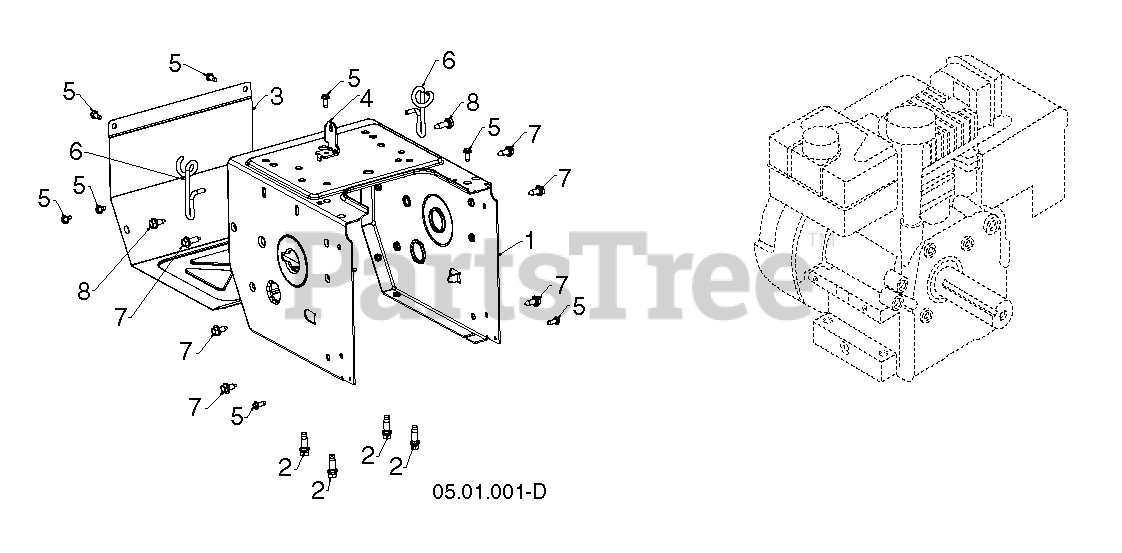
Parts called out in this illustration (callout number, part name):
1	FRAME.GEAR.CASE.ORANGE
2	BOLT 3/8-16X1-1/8
3	COVER COVER.FRAME MS668 ORANGE
4	BRACKET.SHIFTER.SNOW.BLACK
5	SCREW 14-20 X 5/8
6	RP.SUPPORT CABLES WIREFORM
7	BOLT.HEX.HD.WASHER.5/16-18X.75
8	SCREW HEX_SERR_HD_5_16-18X1.0
